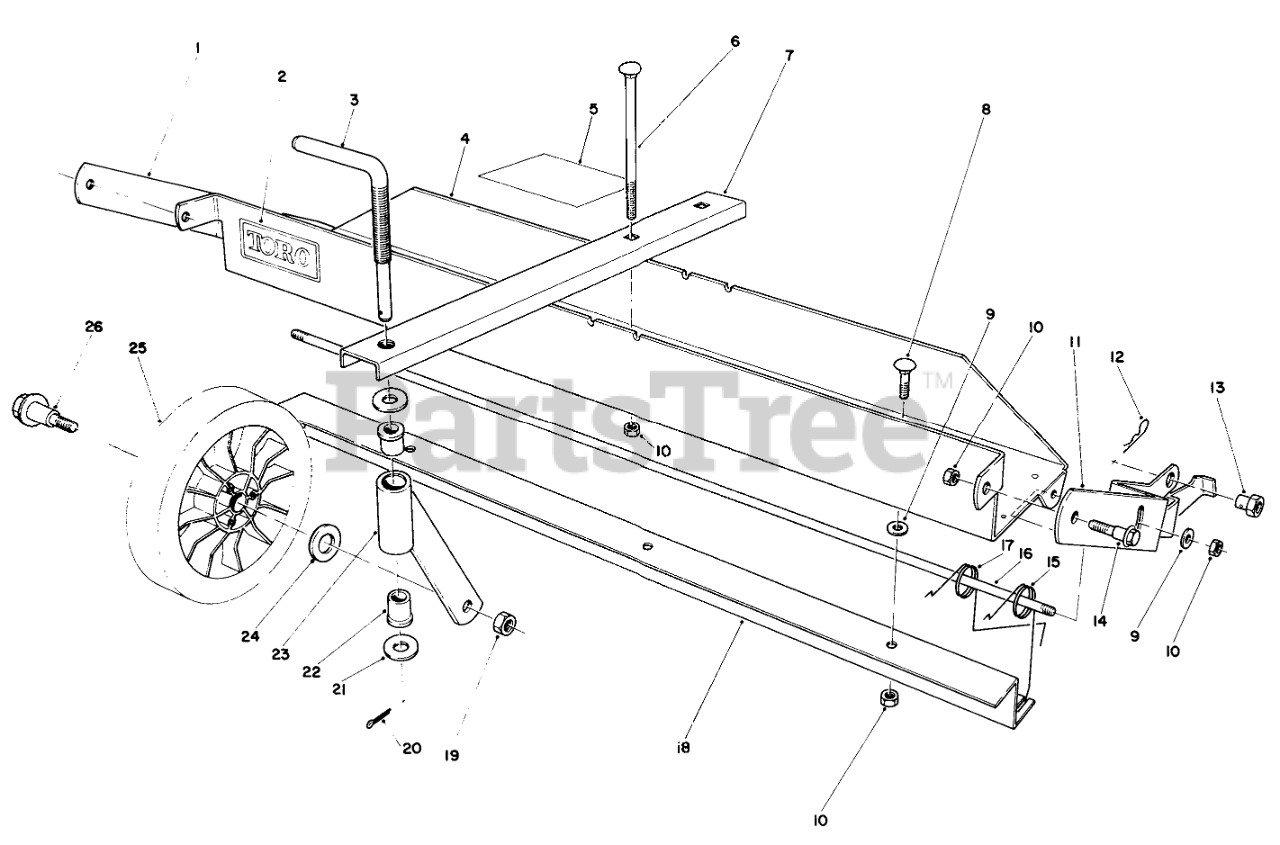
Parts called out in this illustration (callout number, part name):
1	Frame R.H.
2	Decal-Toro
3	CASTOR ADJ ROD
4	Frame-Main (Incl. Ref. #2)
5	Decal-Instruction
6	SCREW-CARR
7	Castor Frame
8	BOLT-CARR
9	WASHER-FLAT
10	NUT-HEX, SIDE DEFORM
11	LH MTG FRAME
12	PIN-COTTER, HAIR
13	PIVOT NUT
14	SCREW-SHOULDER
15	DETHATCHER SPRING
16	SPRING SUPPORT ROD
17	DETHATCHER SPRING
18	SPRING GUIDE STRAP
19	Nut
20	PIN-COTTER
21	WASHER-FLAT
22	FLANGE BUSHING
23	Castor Tube & Support
24	WASHER
25	Wheel Assembly
26	BOLT-WHEEL
